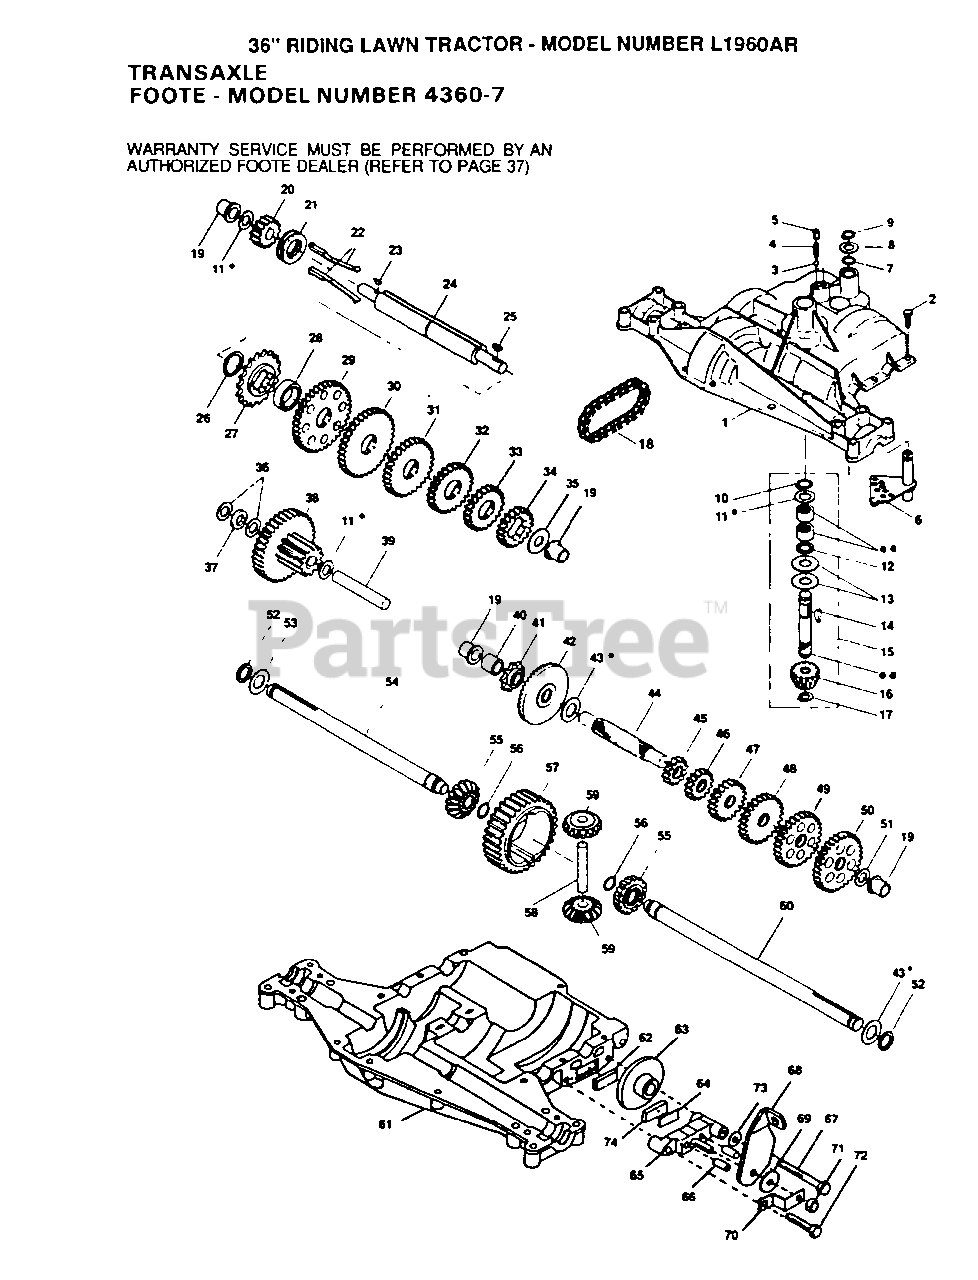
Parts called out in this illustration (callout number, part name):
1	HOUSING UPPER
3	BALL DETENT
4	SPRING, DETENT
5	SCREW, SET
6	ASSY SHIFTER
8	WASHER PLAIN
9	RING RETAINING
10	RING RETAINING
11	WASHER PLAIN
11	WASHER, PLAIN .632 X 1.00 X .026
11	WASHER, PLAIN .632 X 1.00 X .060
13	WASHER, PLAIN .632 X 1.38 X .046
14	KEY WOODRUFF #9
15	ASSY KIT INPUT SHAFT
16	PINION, BEVEL, 14 TEETH
17	RING, RETAINING
18	CHAIN, 24 PITCHES
19	BEARING, FLANGE
20	GEAR SPUR, 14 TEETH
21	COLLAR CLUTCH
22	KEY CLUTCH
23	KEY WOODRUFF #3
24	SHAFT INTERMEDIATE
25	KEY, WOODRUFF, #61
26	RING, RETAINING
27	SPROCKET, 18 TEETH
29	GEAR, SPUR, 37 TEETH
30	GEAR, SPUR, 35 TEETH
31	GEAR, SPUR, 30 TEETH
32	GEAR, SPUR, 25 TEETH
33	GEAR, SPUR, 22 TEETH
35	WASHER, PLAIN .640 X 1.37 X .061
36	WASHER, PLAIN .632 X 1.00 X .026
37	SPACER .630 X 1.00 X .169
38	ASSY GEAR COMB 12&35 TEETH
39	SHAFT IDLER
40	SPACER .635 X .875 X .755
41	SPROCKET, 9 TEETH
42	GEAR, BEVEL, 42 TEETH
43	WASHER PLAIN
43	WASHER, PLAIN .758 X 1.25 X .031
44	SHAFT, DRIVE
45	GEAR, SPUR, 12 TEETH
46	GEAR SPUR, 15 TEETH
47	GEAR, SPUR, 20 TEETH
48	GEAR, SPUR, 25 TEETH
49	GEAR, SPUR, 28 TEETH
50	GEAR, SPUR, 31 TEETH
51	WASHER, PLAIN .632 X 1.00 X .060
53	WASHER PLAIN
54	AXLE LEFT HAND
55	GEAR, MITER, 15 TEETH
56	RING, RETAINING
57	GEAR, SPUR, 32 TEETH
58	SHAFT, CROSS
59	GEAR, MITER, 15 TEETH
60	AXLE, R.H.
61	HOUSING LOWER
62	PUCK, FRICTION
63	DISC, BRAKE
65	JAW, BRAKE
66	PIN, DOWEL
67	SCREW TAPPING
68	LEVER, ACTUATING
69	WASHER, PLAIN .321 X 1.00 X .055
70	BRACKET, ANTI-ROTATION
71	LOCKNUT 5/16-24
72	SCREW TAPPING
73	WASHER PLAIN
74	PUCK, FRICTION
